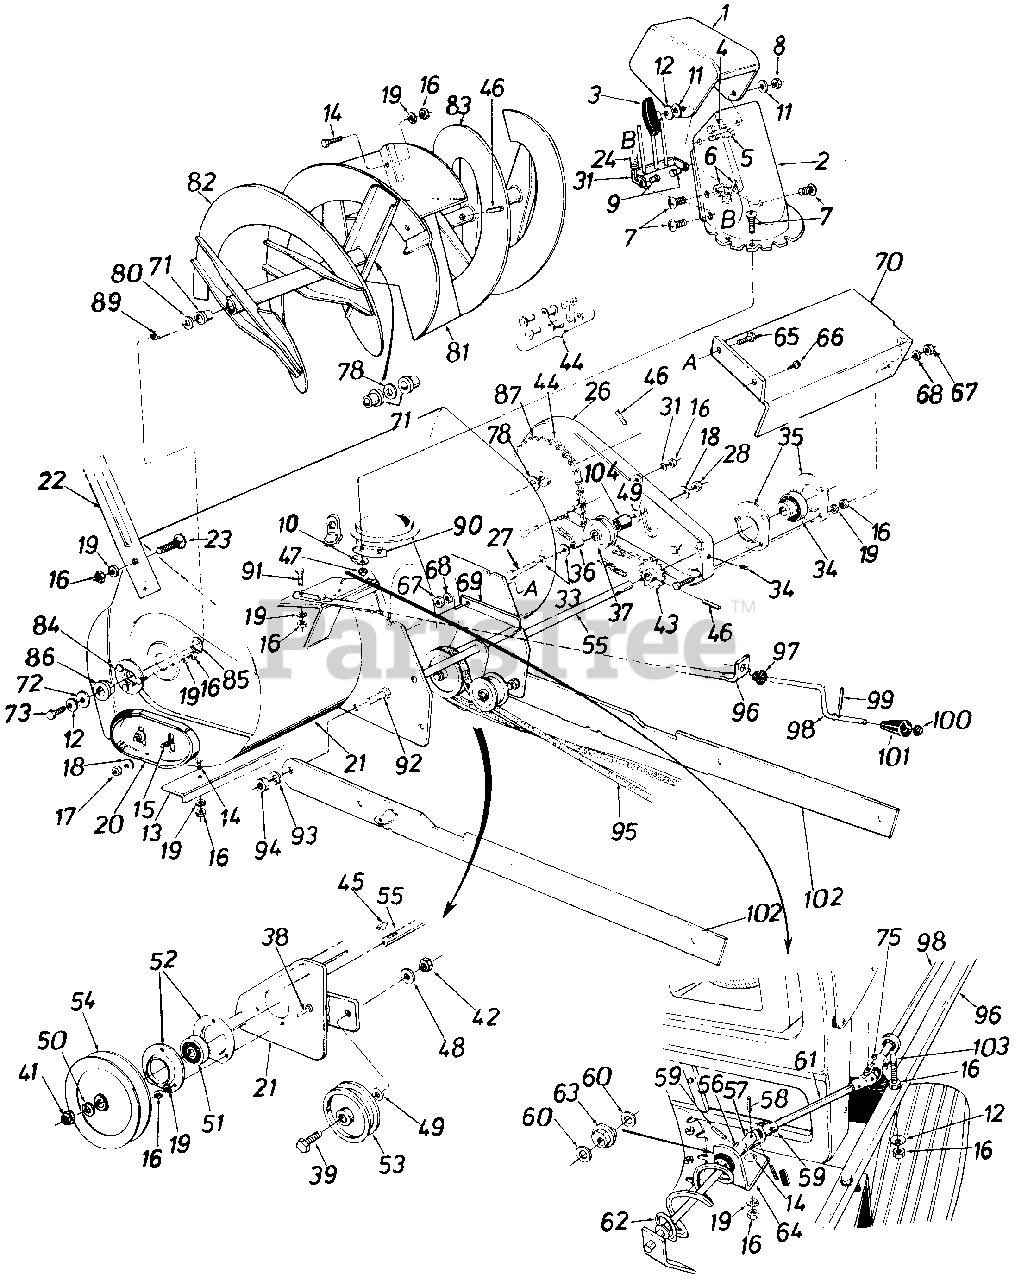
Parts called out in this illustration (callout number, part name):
1	Upper Chute
2	Lower Chute
3	Knob Handle Ass'y.
4	Truss Mach. Scr. 5/16-18 x .75" Lg.
5	Carriage Bolt 5/16-18 x 1.0"
6	Hex Cent. L-Nut 5/16-18 Thd.
7	Truss Mach. Scr. 1/4-20 x .75" Lg.
8	Hex Cent. L-Nut 5/16-18 Thd.
9	Shld. Nut 1/4-20 Thd.
10	Fl. Wash. 1/4" I.D.
11	Fl.-Wash. .344" I.D. x 1.125"
12	Bell. Wash. .345" I.D. x .88"
14	Carriage Bolt 5/16-18 x .62"
15	Carriage Bolt 3/8-16 x .62"
16	Hex Nut 5/16-18 Thd.
17	Hex Jam Nut 3/8-16 Thd.
18	Bell. Wash. .40 I.D. x .88"
19	L.-Wash. 5/16" I.D.
20	Slide Shoe
21	Spiral Hsg. Ass'y.-36"
22	Guide Blade
23	Carriage Bolt 5/16-18 x .62"
24	Extension Spring
26	Chain Guard Ass'y.
27	Hex Bolt 3/8-16 x 2.00 4.
28	Hex Inst.-Nut 3/8-16 Thd.
33	Fl.-Wash. .385" I.D. x.87" O.D.
34	Ball Brg. .75" I.D.
35	Flangette
36	Spacer .375" I.D. x .60" O.D.
37	Fl.-ldler w/Flanges 1.875
38	Hex Sems Bolt 5/18 x.75" Lg.
39	Hex Bolt 3/8-16 x 1.75" Lg.
41	Hex Jam Nut 3/4-10 Thd.
42	Hex Jam Nut 3/8-16 Thd.
43	Sprocket Ass'y.-14 Teeth
44	#420 Chain x 1/2" Pitch-77 Links
45	#61 Hi-Pro-Key 3/16 x 5/8"
46	Spring Pin Spir. 5/16" Dia. x 1.75" Lg.
47	Hex L-Nut 1/4-20 Thd.
48	L.-Wash. 3/8" I.D.
49	Fl.-Wash. .406" I.D. x 1.25"
50	Spring L.-Wash. 3/4" I.D.
51	Self Allgning Brg.
52	Flangette
53	Idler Pulley
54	5/8 V Pulley .75" I.D. x 6"
55	Drive Shaft Ass'y.
56	Joint Brkt. Ass'y.
58	Oval Head Rivet
59	Spiral Pin 1/8" Dia.
60	Fl.-Wash. .385" I.D. x .62"
61	Chute Crank Ext. Rod
62	Chute Crank Ass'y. R.H.
63	Plastic Bushing .380" I.D.
64	Chute Crank Brkt.
65	Hex Bolt 1/4-20 x .62" Lg.
66	Hex Wash. S-Tap Scr. 1/4-20 x.50" Lg.
67	Hex Nut 1/4-20 Thd.
68	L.-Wash. 1/4" I.D.
70	Drive Shaft Cover
71	Plastic Bushing
72	Washer.39" I.D. x 1.75" O.D
73	Hex Bolt 5/16-18 x .88" Spec
75	Cotter Pin 3/32" Dia.
78	Fl.-Wash. 1.03" I.D. x 1.62"
80	Fl.-Wash. 1.0" x 1.75"
85	Snap Ring for 1.50" Shaft
86	Flange Brg. w/flats 1.00" I.D.
87	Sprocket Hub Ass.y. 40 Teet
90	Chute Flange Keeper
91	Hex Bolt 5/16-18 x 1.5" Lg.
92	Hex Bolt 1/"-13 x 1.25" Lg.
93	L.-Wash. 1/2" I.D.
94	Hex Nut 1/2"13 Thd.
95	"V" Belt
98	Chute Crank 34.5" L.g
99	Roll Pin .12 Dia. x .63
100	Push Nut 3/8" Rod
101	Knob Black
102	Linkage Arm
103	Eye Bolt 5/16-18 x 3.0" Lg.
104	Idler Spacer
